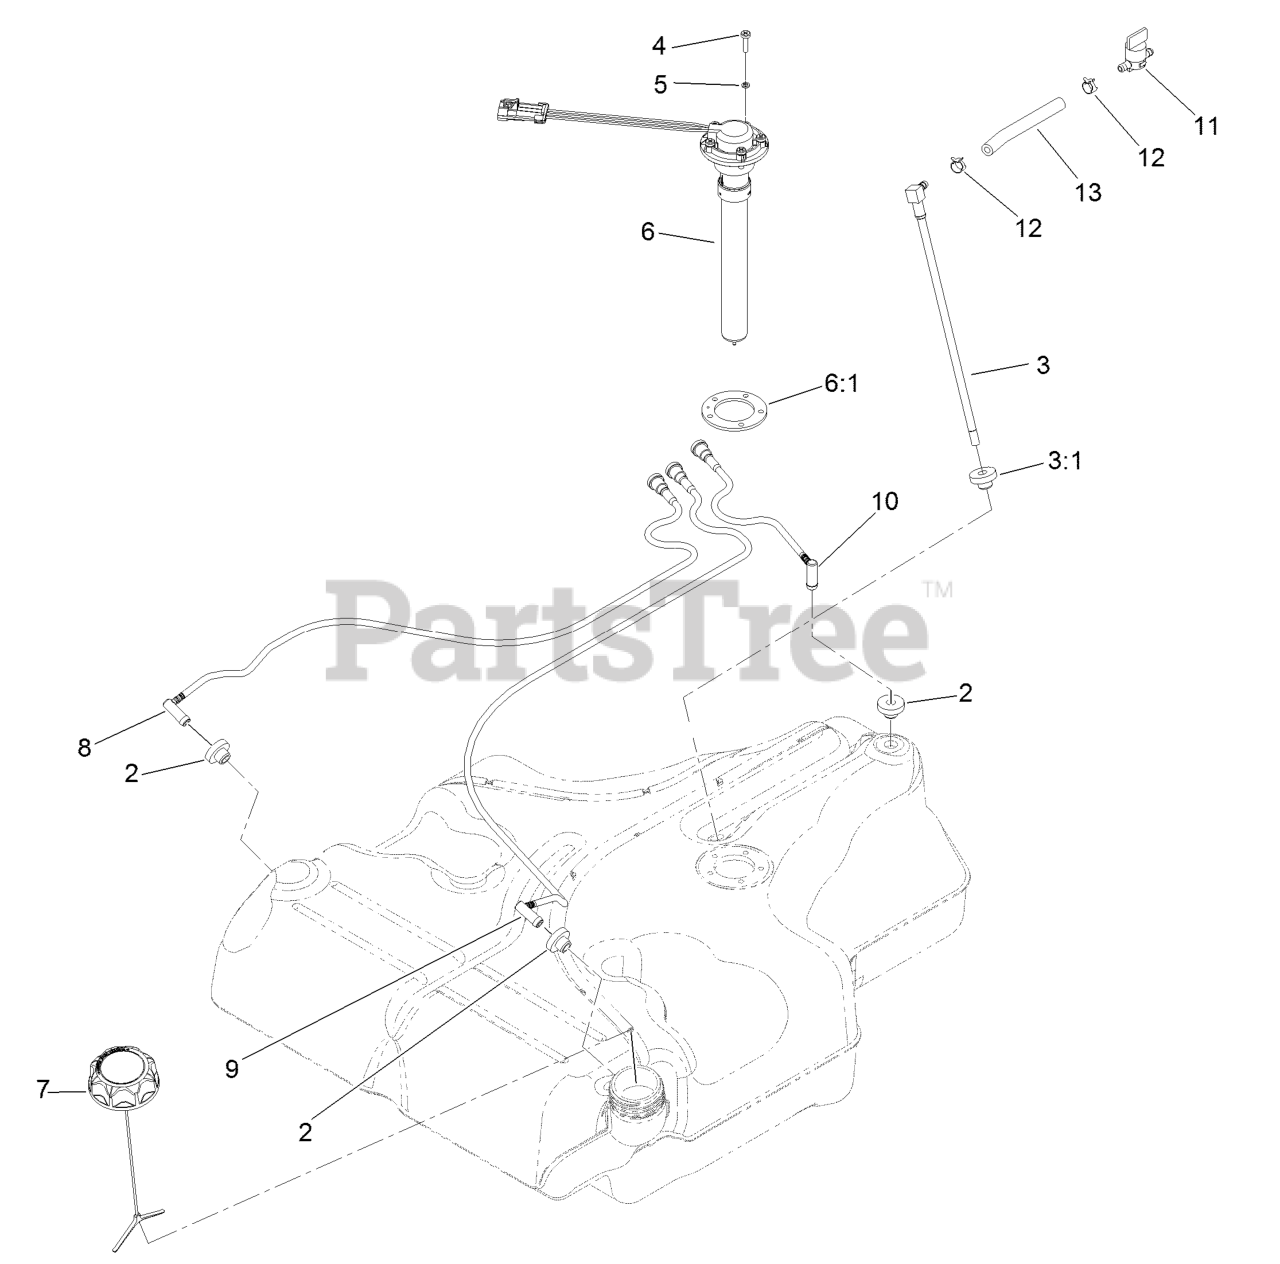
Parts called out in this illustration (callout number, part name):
2	BUSHING
3	FUEL LINE KIT (WITH GROMMET)
3:1	BUSHING
4	SCREW-PAN
5	WASHER-LOCK
6:1	GASKET-SENDER, FUEL
8	RH VENT LINE KIT (WITH GROMMET)
9	LH VENT LINE KIT (WITH GROMMET)
10	REAR VENT LINE KIT (WITH GROMMET)
11	VALVE-FUEL
12	CLAMP-HOSE
13	HOSE-FUEL
